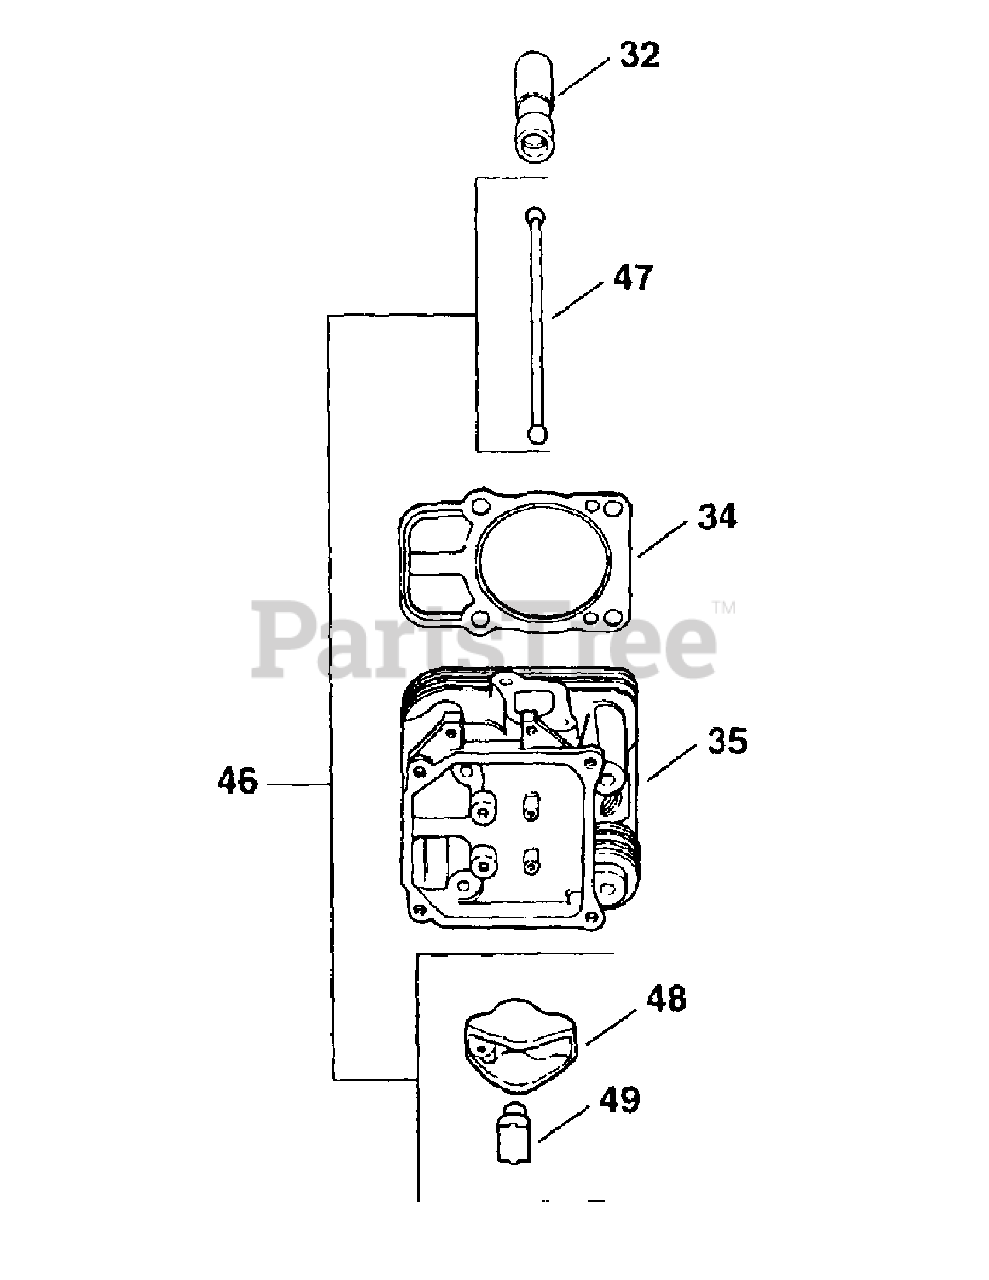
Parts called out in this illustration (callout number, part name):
32	Lifter, Valve
34	Gasket, Cylinder Head
46	Kit, Valve Train
47	Rod, Push
48	Arm, Rocker
49	Pivot, Cylindrical Rocker Arm
